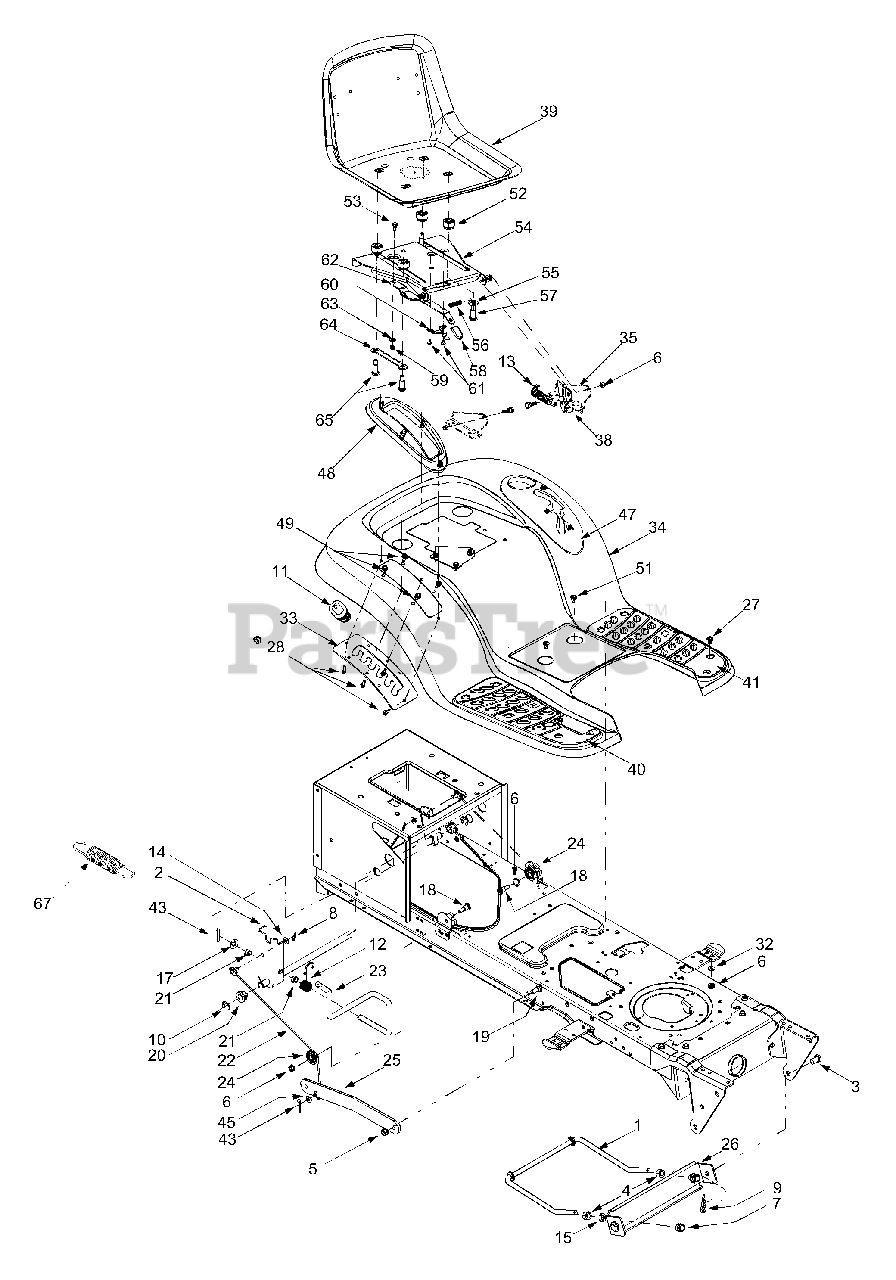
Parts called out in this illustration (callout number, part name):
1	Deck Stabilizer Rod
4	Hex Nut, 1/2-13
5	Flange Lock Nut, 3/8-16
6	Flange Lock Nut, 5/16-18
7	Hex Nut, 1/2-13
8	Internal Cotter Pin
9	Internal Cotter Pin
10	E-Ring
11	Handle Grip
12	Torsion Spring
13	Extension Spring, .84 x 4.6
14	Flat Washer, 5/16
15	Lock Washer, 1/2
16	Flat Washer, .531 x 1.062 x .134
17	Flat Washer, .51 x 1.12 x .06
18	Hex Cap Screw, 5/16-18 x .62
19	Shoulder Screw, 3/8-16
20	Hex Flange Bearing
21	Snap Flange Bearing
22	Lift Cable, 16.16
23	Lift Handle
24	Roller Pulley
27	Carriage Bolt, 5/16 x .62
28	Self-tapping Screw, 5/16-18 x .625
32	Flat Washer, .349 x 1.0 x .063
37	Speed Clip
38	Seat Lift Bracket
39	Seat: High Back
40	Foot Pad RH, Rubber
41	Foot Pad LH, Rubber
42	Foot Pad Clips
43	Cotter Pin
45	Flat Washer, .344 x .62
47	Lift Lever Cover
48	Shift Lever Cover w/ Cup Holder
49	Self-Tapping Screw, 1/4-15 x .75
51	Self-tapping Screw, 1/4-20 x 0.5
52	Spacer: Seat Adjustment
53	Shoulder Screw 1/4-20
56	Compression Spring
57	Shoulder Screw 3/8-16
58	Grip: Seat Adjustment
59	Lock Nut 1/4-20
60	Seat Stop
61	B Screw #10-16 x 0.375
63	Flat Washer
64	Seat Adjustment Selector
65	Shoulder Screw 3/8-16
66	Hex Washer Hd. Screw
67	Extension Spring (Lift Assist)
